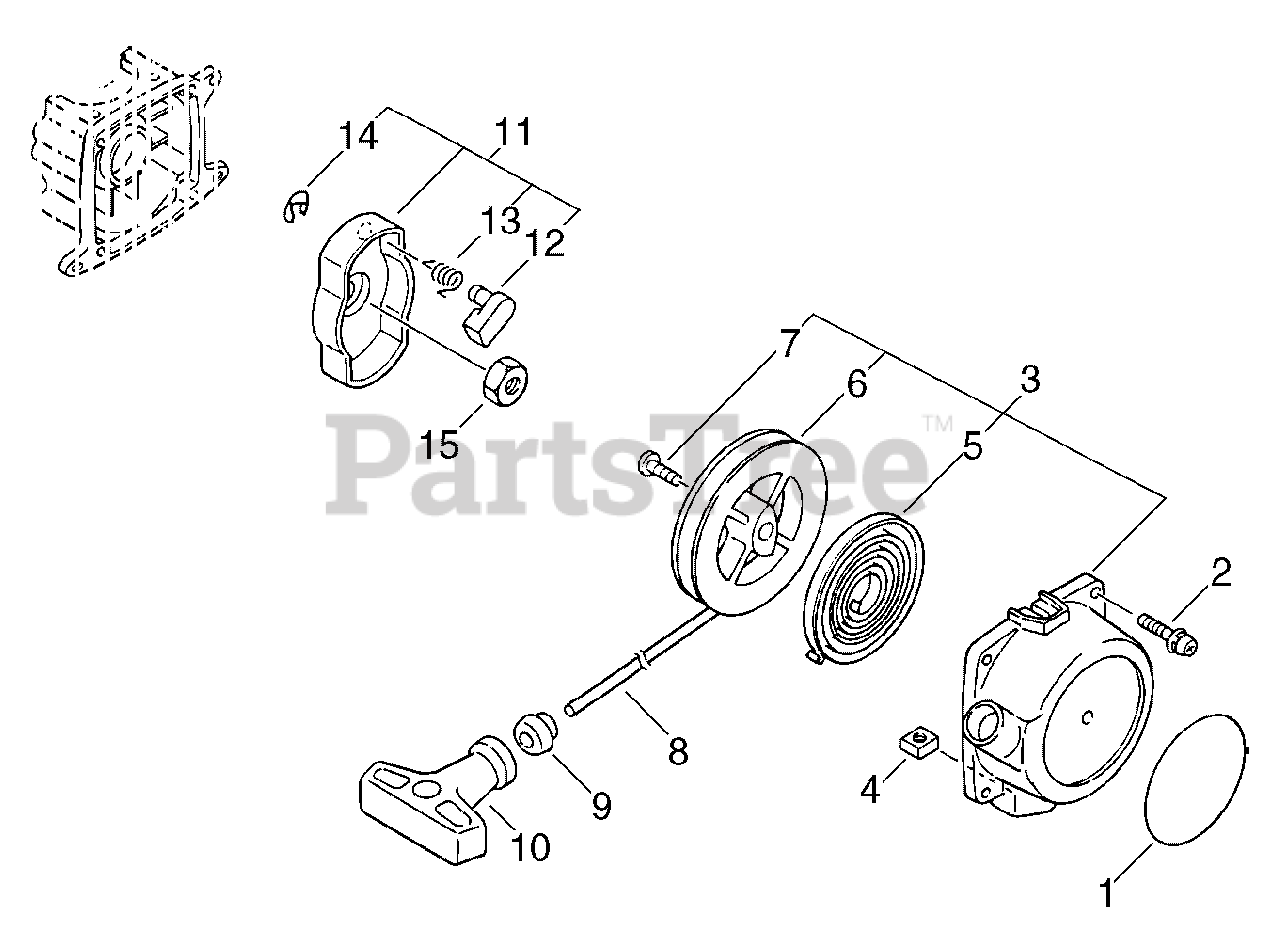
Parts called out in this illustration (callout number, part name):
1	LABEL - ECHO
2	SCREW - 4X14
3	STARTER ASSY
4	NUT
5	SPRING, REWIND
6	REEL, ROPE
8	ROPE, STARTER
9	GUIDE, ROPE
10	GRIP, STARTER
11	STARTER PAWL ASSY
12	PAWL, STARTER
13	SPRING, RETURN
14	RING, RETAINING - 4
